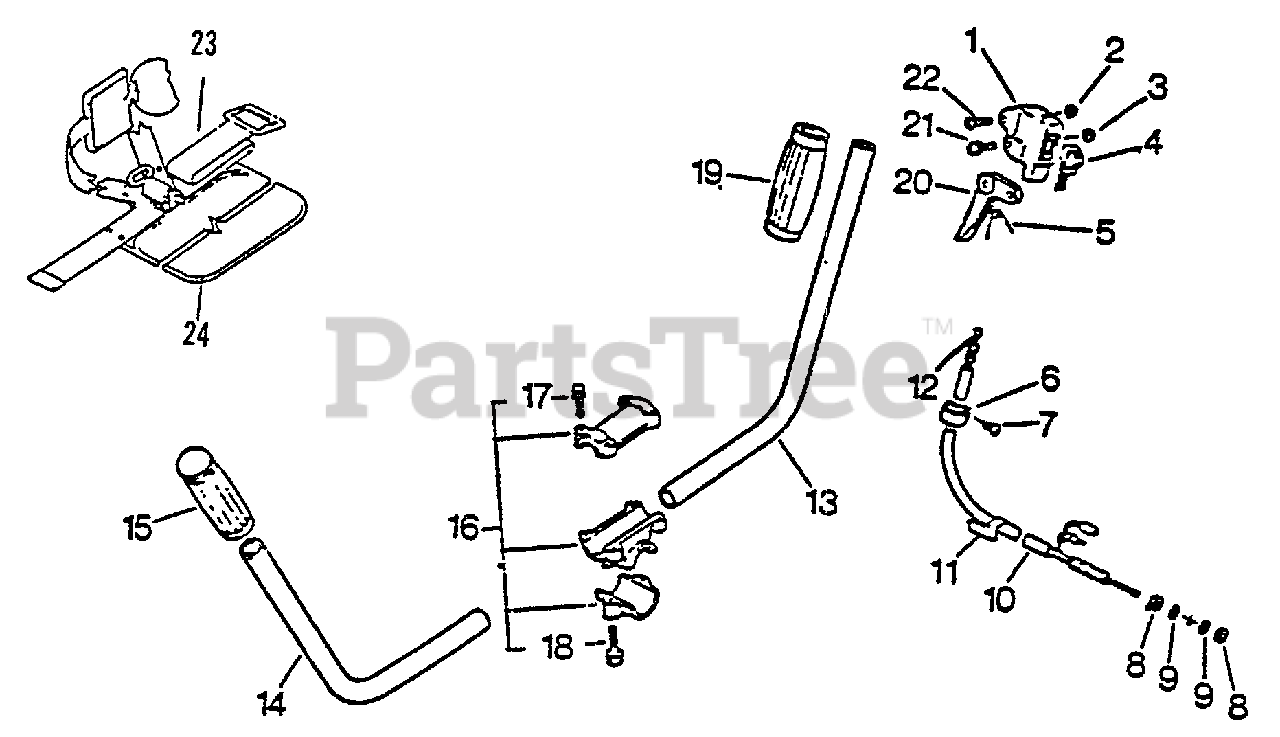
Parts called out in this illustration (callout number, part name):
1	BRACKET, THROTTLE
2	NUT, LOCK M5
3	NUT M5
4	SWITCH, ON-OFF
7	SCREW 5×10
9	WASHER 6.5×11.5×0.8
12	CABLE, THROTTLE
14	HANDLE, LEFT
15	GRIP, HANDLE
16	HANDLE BRACKET KIT
17	BOLT - 5×25
18	BOLT - 6×30
20	TRIGGER, THROTTLE
21	SCREW 5×25
23	PAD, HIP
24	SHOULDER STRAP ASSY
